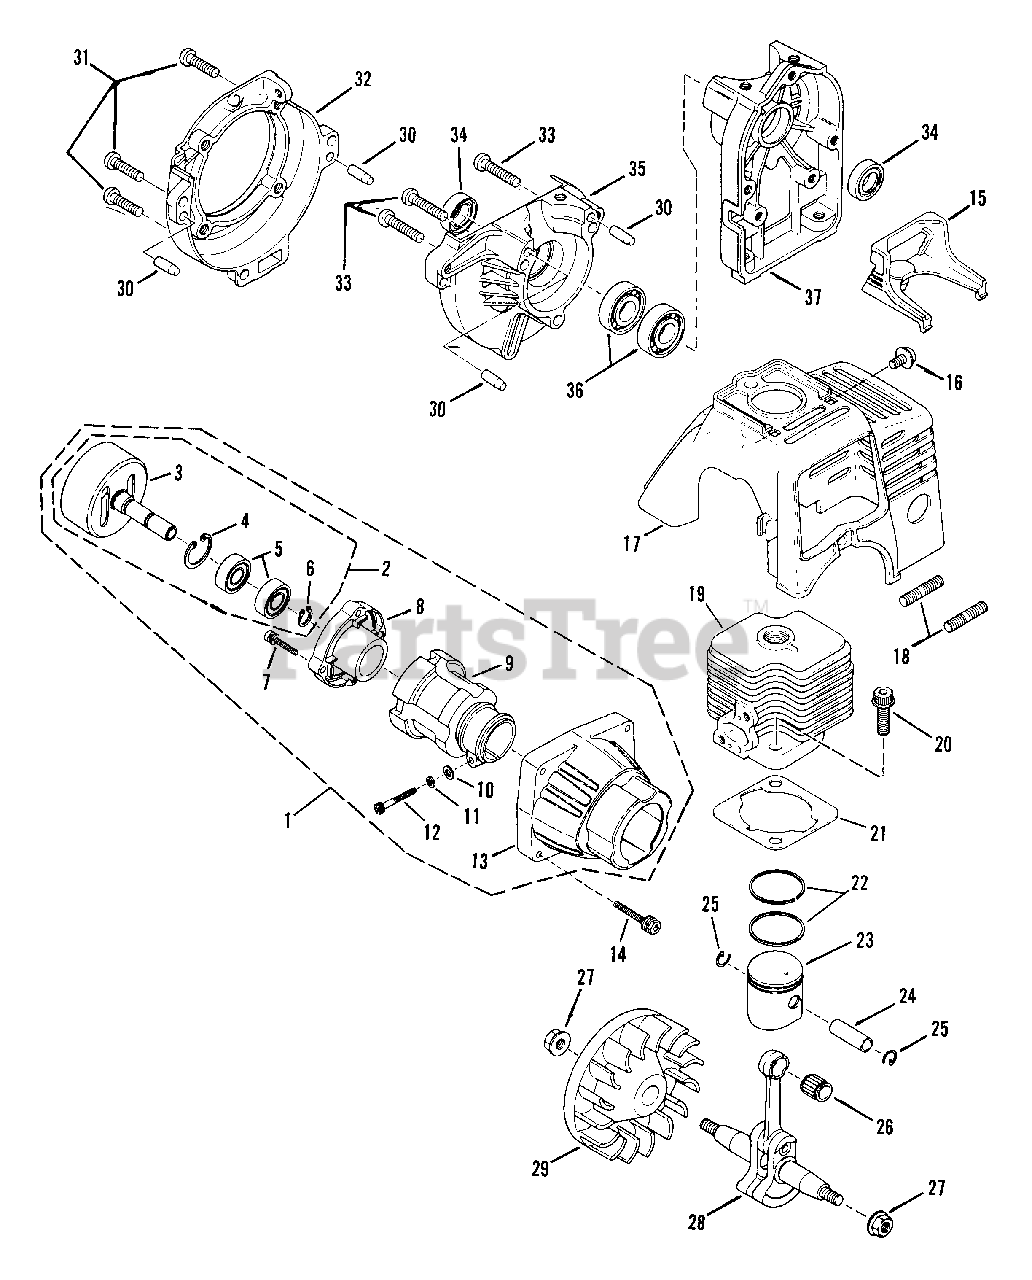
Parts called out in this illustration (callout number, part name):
1	ASSEMBLY, Clutch Case
2	ASSEMBLY, Clutch Drum
3	DRUM, Clutch
4	RING, Snap 26mm
5	BEARING
6	RING, Snap 10mm
7	SCREW, M5 x 20mm
8	COVER, Clutch Bearing
9	RING, Insert
10	WASHER, Flat M5
11	WASHER, Lock M5
12	SCREW, M5 x 25mm Socket
13	CASE, Clutch
14	BOLT, M6 x 28mm Hex Head
15	GUARD, Spark Plug
16	SCREW, M5 x 12mm
17	COVER, Cylinder
18	BOLT, Stud, M6 x 16mm
19	CYLINDER
20	BOLT, Flange
21	GASKET, Cylinder
22	RING, Piston
23	PISTON
24	PIN, Piston
25	CLIP, Piston Pin
26	BEARING, Needle
27	NUT, Conical
28	CRANKSHAFT ASSEMBLY
29	FLYWHEEL
30	PIN, Dowel
31	BOLT/Washer
32	CASE, Fan
33	SCREW, M5 x 25mm
34	SEAL, Oil
35	CASE, Drive
36	BEARING, Ball
37	CASE, Starter
